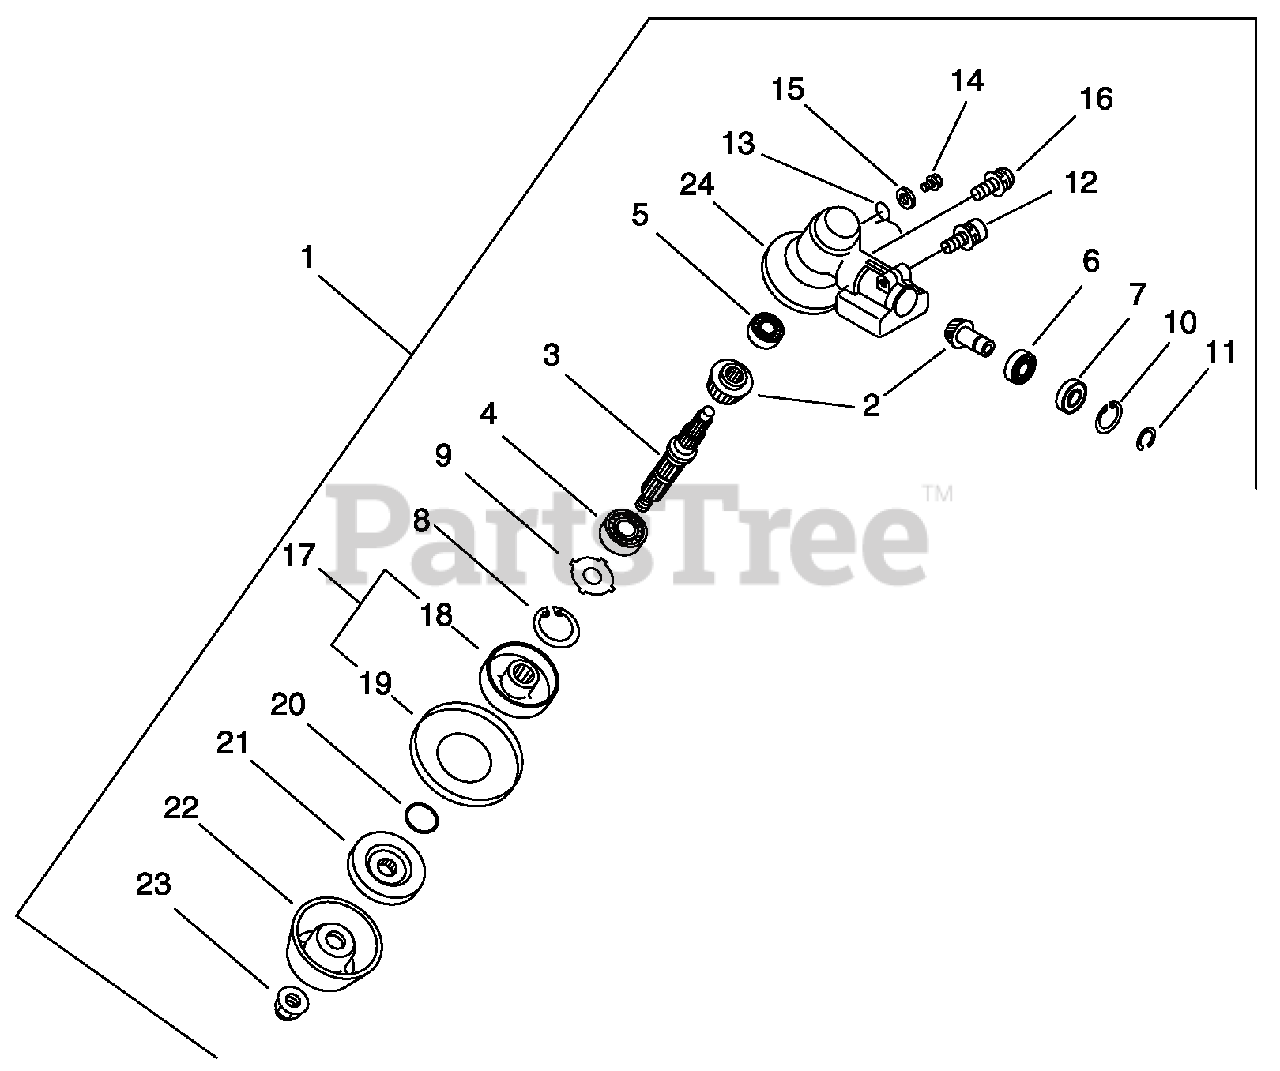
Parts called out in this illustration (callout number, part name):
1	GEAR CASE ASSY
2	GEAR SET
3	GEAR - SHAFT
4	BEARING, BALL - 6201
5	BEARING, BALL - 626
6	BEARING, BALL - 6900
7	BEARING, BALL - 6900Z
8	RING, RETAINING - 32
10	RING, RETAINING - 22
11	RING, RETAINING - 10
12	SCREW - 6X25
13	SPRING
14	BOLT - 8X8
15	WASHER - 8
16	SCREW - 5X10
17	BLADE ADAPTER KIT
18	ADAPTOR, BLADE - UPPER
19	RETAINER, BLADE
20	O-RING - 12
21	ADAPTOR, BLADE - LOWER
23	NUT - 10
24	CASE, GEAR
